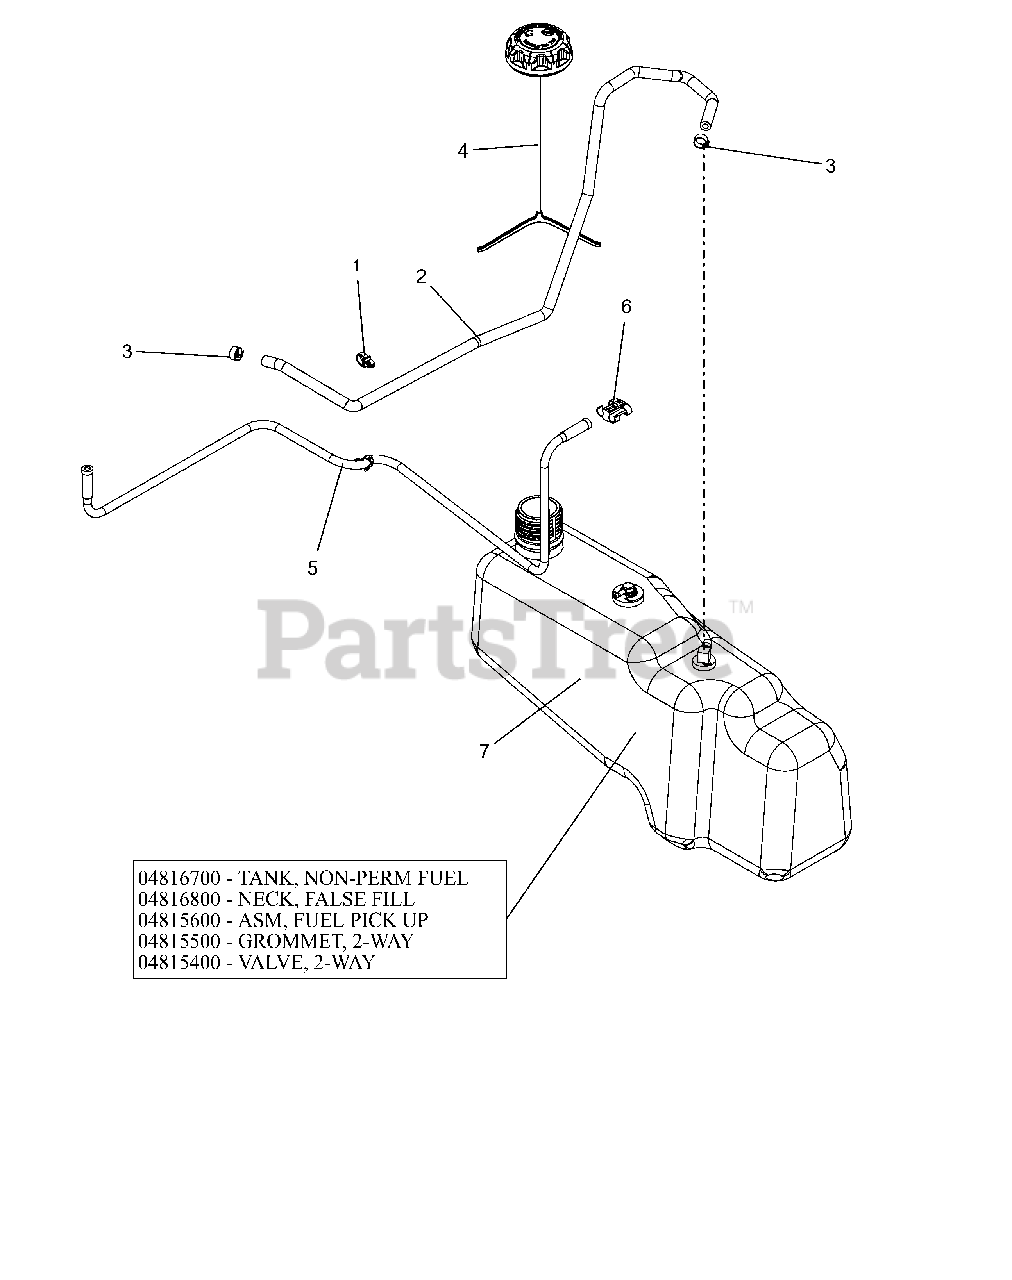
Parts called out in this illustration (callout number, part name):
1	ROUTING CLIP (1/2" ID)
2	HOSE, .25 LOW-PERM BULK GAS
3	CLAMP, FUEL LINE
4	CAP, FUEL VENT-IN 2.25" RATCH.
5	LINE, FUEL VENT KOHLER
6	CLIP, T, .38-.50
7	ASM,TANK NON-PERM FUEL
7	TANK, ZOOM/ZT NON-PERM, FUEL
7	NECK, FALSE FILL ZOOM/ZT
7	ASM, FUEL PICK-UP ZOOM/ZT 2015
7	GROMMET, 2-WAY
7	VALVE, 2-WAY
